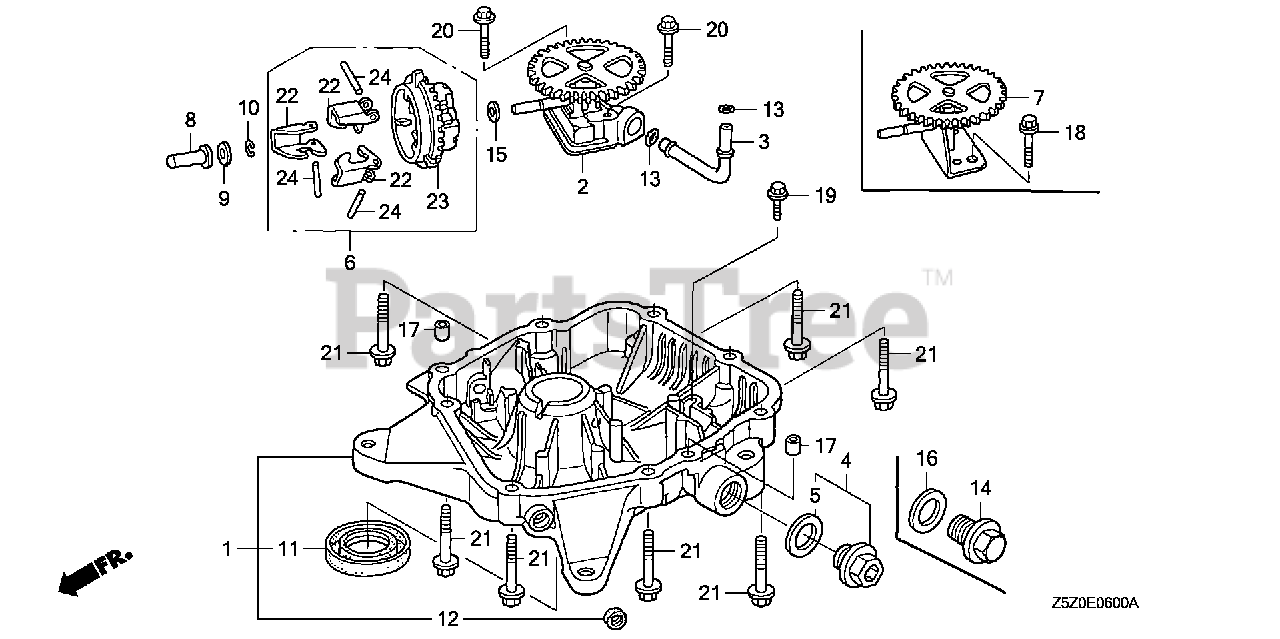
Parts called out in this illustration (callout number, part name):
1	PAN ASSY., OIL
2	PUMP ASSY., OIL
3	PIPE, OIL PUMP
6	GOVERNOR ASSY.
8	SLIDER, GOVERNOR
9	WASHER (6X16)
10	CLIP, GOVERNOR HOLDER
11	OIL SEAL (31X50X8)
12	OIL SEAL (10X16X4.5)
13	O-RING (7.5X2.3)
14	BOLT, DRAIN PLUG (20MM)
15	WASHER, PLAIN (6MM)
16	WASHER, DRAIN PLUG (20MM)
17	PIN, DOWEL (8X14)
19	BOLT, FLANGE (6X22)
20	BOLT, FLANGE (6X30)
21	BOLT, FLANGE (8X40)
22	WEIGHT, GOVERNOR
23	HOLDER, GOVERNOR WEIGHT
24	PIN, GOVERNOR WEIGHT
